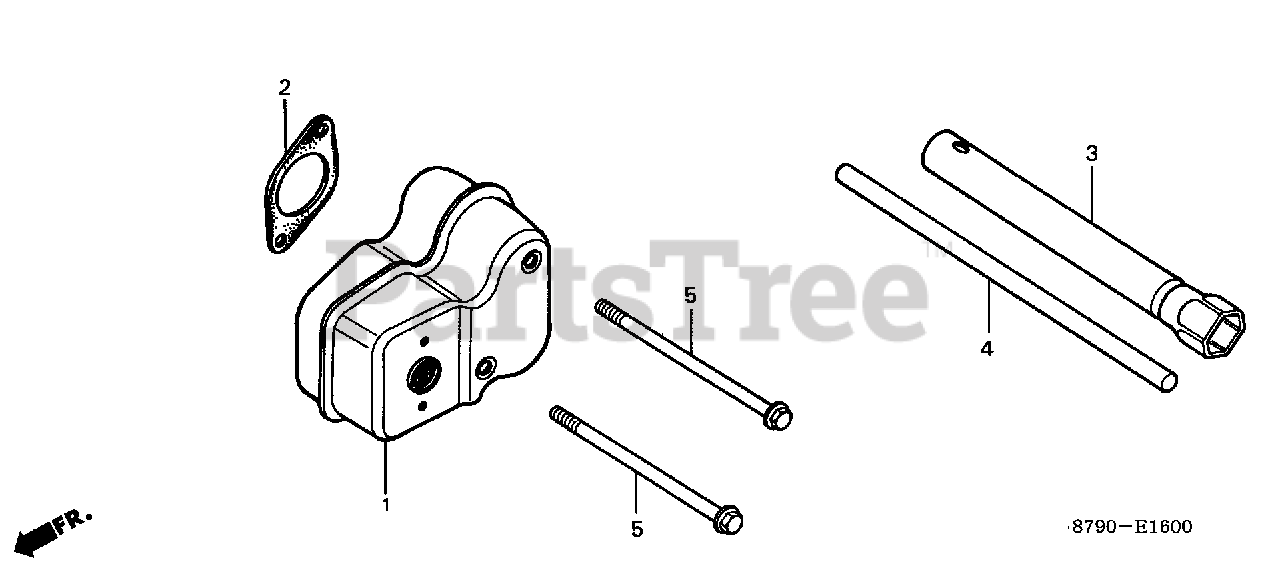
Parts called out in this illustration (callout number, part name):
2	GASKET, MUFFLER
3	WRENCH, SPARK PLUG
4	HANDLE, BOX WRENCH
5	BOLT, FLANGE (6X95)
